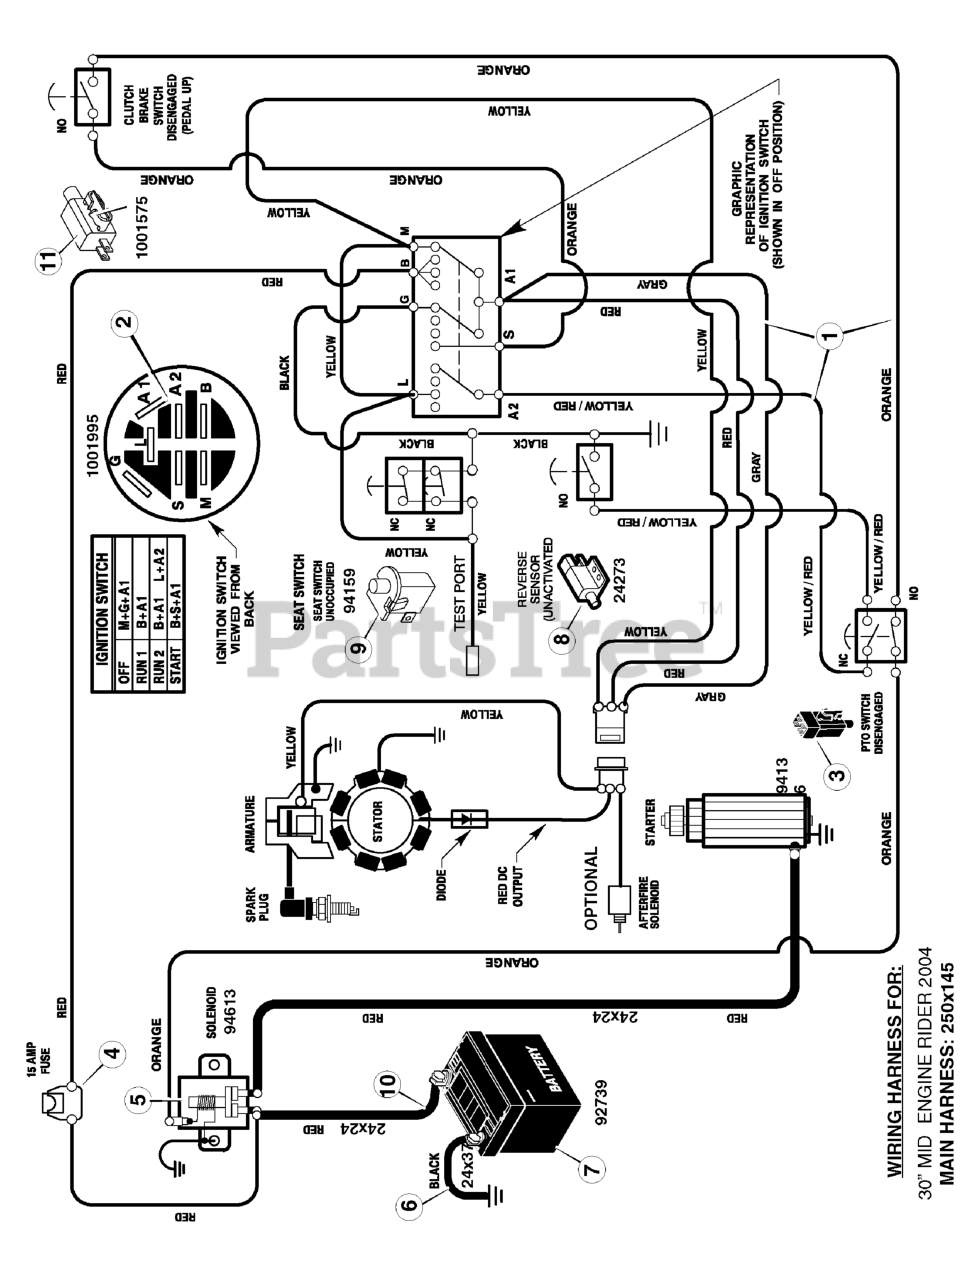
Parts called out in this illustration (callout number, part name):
1	Harness, Chassis Wire
2	Switch, Ignition
3	Switch, Limit (PTO)
5	Solenoid
6	Cable, Battery Ground
7	Battery
8	Switch, Select Reverse
9	Switch, Seat Sensor
11	Switch, Clutch Brake
